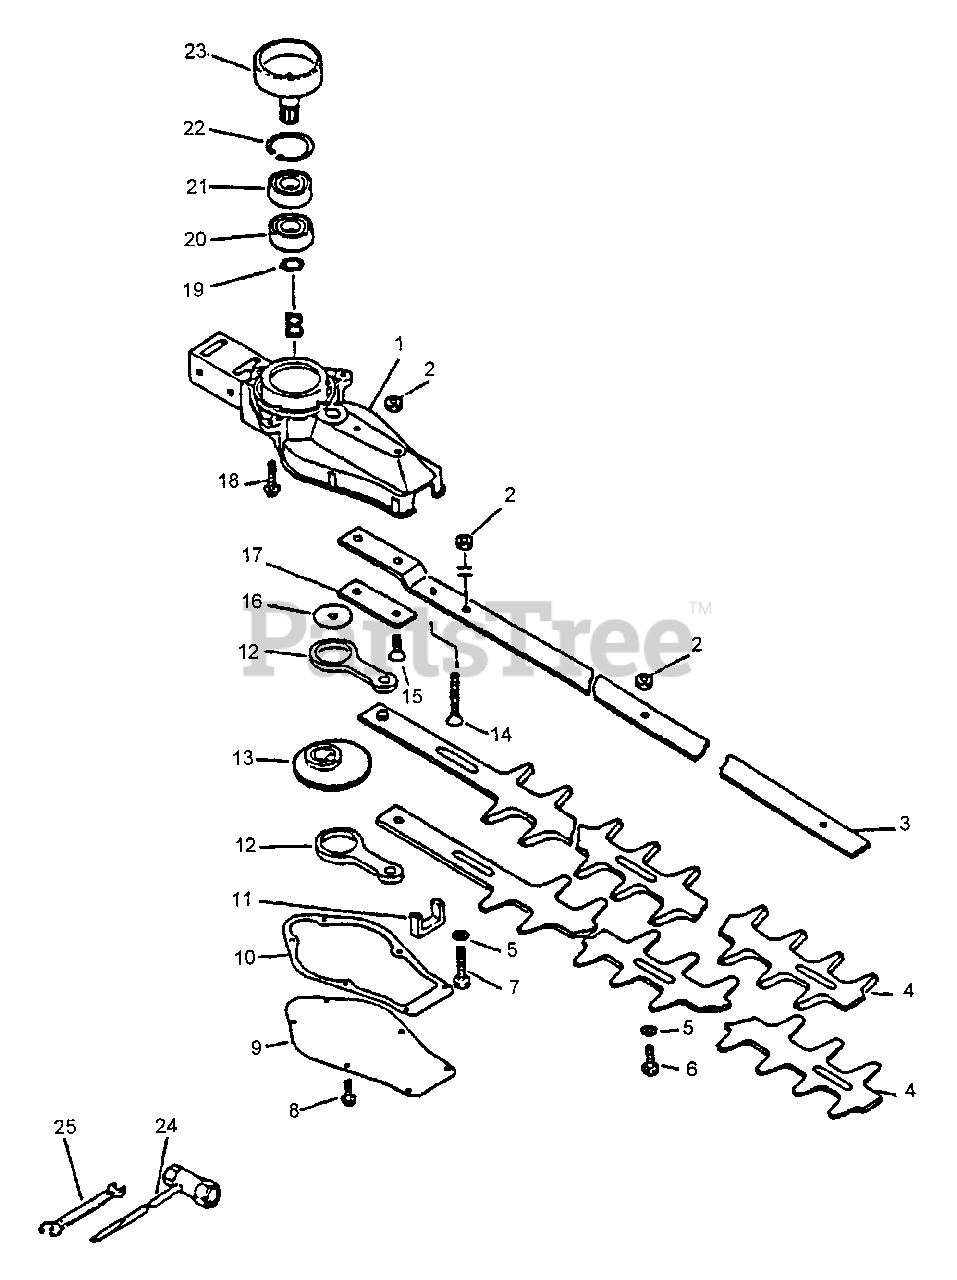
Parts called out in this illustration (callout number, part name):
1	CASE, GEAR
2	LOCKNUT - 6
3	SUPPORT, BLADE
3	SUPPORT, BLADE - 20" (50cm)
4	BLADE - 17" (43cm)
4	BLADE - 20" (50cm)
5	WASHER - 6
7	BOLT - 6X35
8	SCREW - 4X10
9	LID, GEAR CASE
10	GASKET, GEAR CASE
11	SEAL, FELT
12	ROD, CONNECTING
13	GEAR - DRIVE
14	SCREW - 5X30
15	SCREW - 6X25
18	SCREW - 5X20
19	RING, RETAINING - 14
20	BEARING, BALL - 6202
21	BEARING, BALL - 6202
22	RING, RETAINING - 35
23	DRUM, CLUTCH
24	T-WRENCH - 13X19mm
25	SPANNER - 8X10mm
